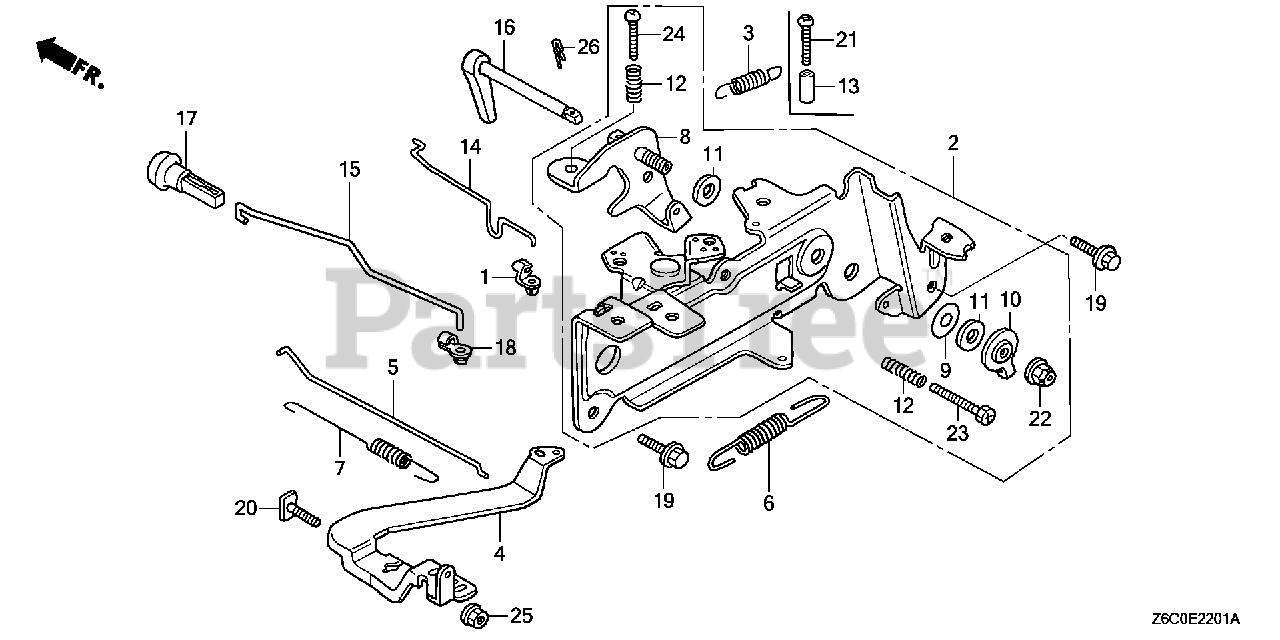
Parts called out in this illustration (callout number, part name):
1	JOINT, ROD
2	CONTROL ASSY.
3	SPRING, STARTER
4	ARM, GOVERNOR
5	ROD, GOVERNOR
6	SPRING, GOVERNOR (MANUAL)
7	SPRING, THROTTLE RETURN
8	ARM, CONTROL
9	SPRING, LEVER
10	WASHER, CONTROL ARM
11	SPACER, CONTROL LEVER
12	SPRING, CONTROL ADJUSTING
13	COLLAR, STOPPER
14	ROD, CHOKE CONTROL
15	ROD, CHOKE KNOB
16	LEVER ASSY., THROTTLE
17	KNOB, CHOKE
18	BUSH, LINKAGE
19	BOLT, FLANGE (6X14) (CT200)
20	BOLT, GOVERNOR ARM
21	SCREW, RECESSED (5X25)
22	NUT, SELF-LOCK (6MM)
23	BOLT, RECESSED (5X25)
24	SCREW, PAN (5X25)
25	NUT, FLANGE (6MM)
26	PIN, LOCK (10MM)
